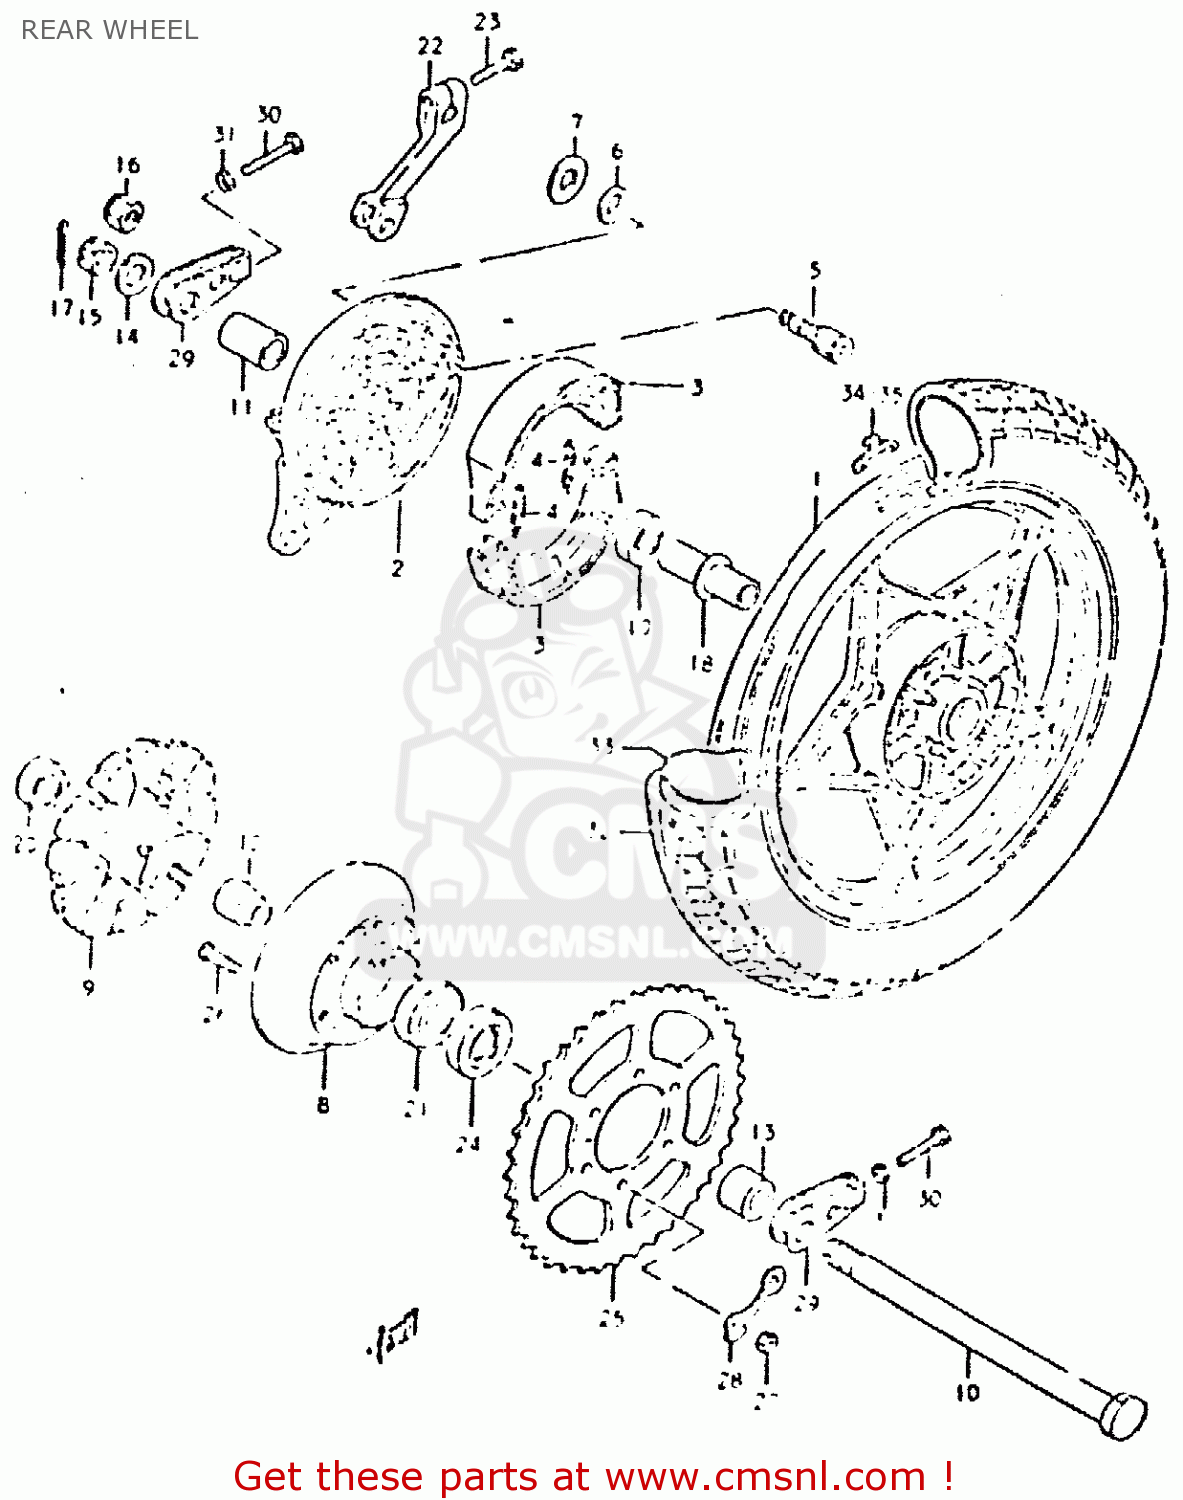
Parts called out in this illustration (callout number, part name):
1	WHEEL,REAR
2	PANEL,REAR HUB
3	SHOE,BRAKE
4	SPRING,BRAKE SHOE
5	CAM,FRONT BRAKE
6	O-RING,BOSS
7	WASHER (15X24X1.6)
8	DRUM,REAR SPROCKET MOUNT
9	ABSORBER,RR HUB SHOCK
10	AXLE,REAR
11	SPACER(17.5X28X44.8)
12	SPACER,REAR HUB BEARING
13	SPACER(17X30.5X22.3)
14	WASHER (17X30X3.2)
15	NUT
17	PIN,COTTER
18	SPACER (17.6X24X57)
19	BEARING
20	BEARING
21	BEARING
22	LEVER,RR BRAKE CAM
23	BOLT
24	SEAL,OIL(30.5X52X8)
25	SPROCKET,REAR (NT:43)
26	BOLT
27	NUT
28	WASHER
29	ADJUSTER,CHAIN
30	BOLT 8X50
31	NUT
32	TIRE
33	TUBE ASSY,WHEEL,INNER 4.60-16
34	BALANCER,WHEEL
35	BALANCER,WHEEL
